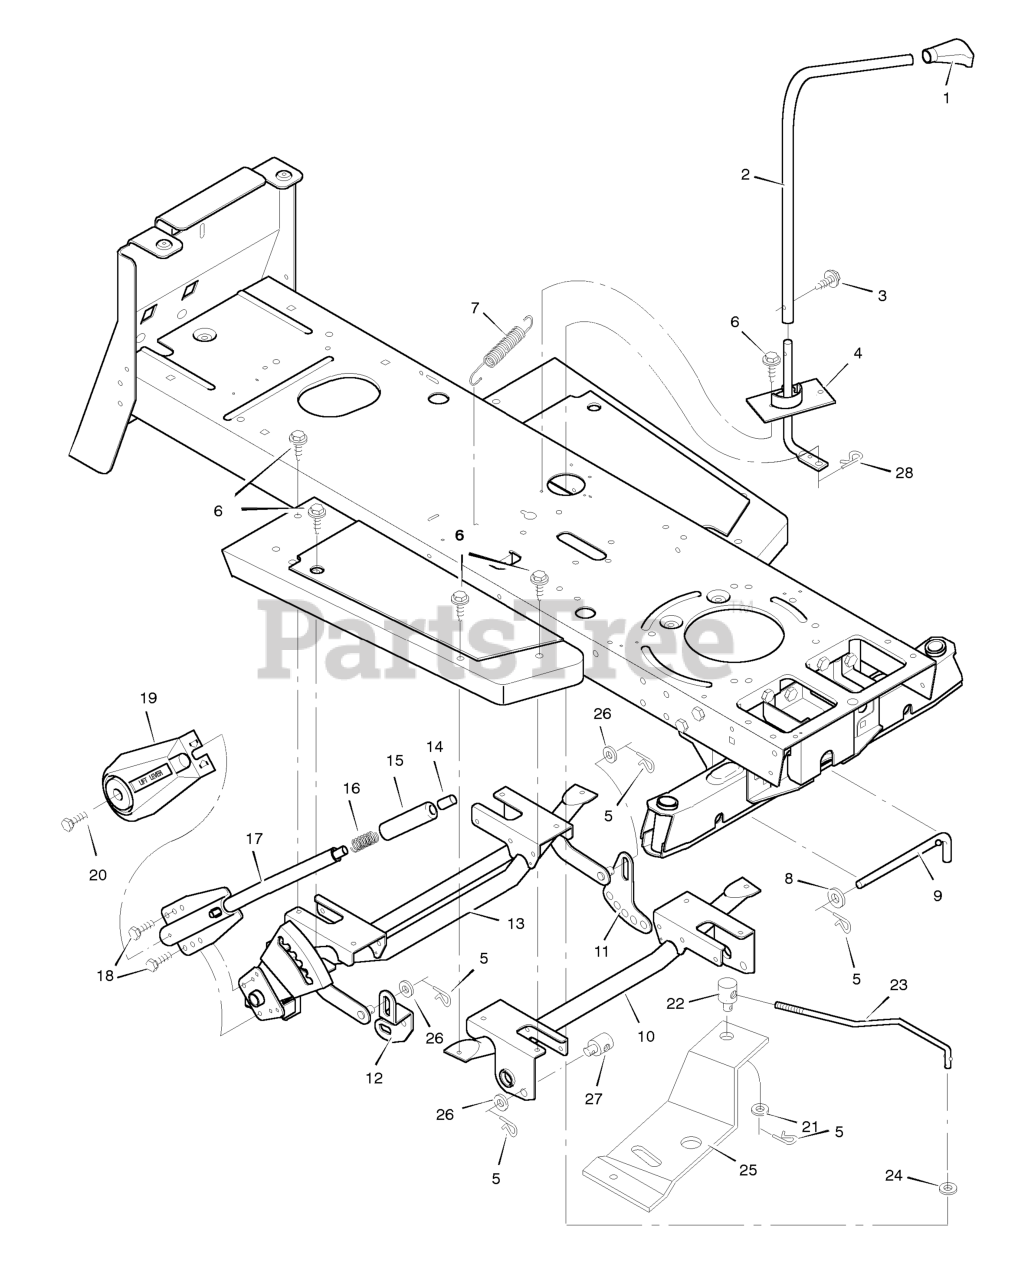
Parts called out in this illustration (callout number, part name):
1	Grip
2	Lever, Blade Control
3	Screw, Hex
4	Control Assembly, Blade
5	Pin, Hair
7	Spring, Extension
9	Pin, Pull
10	Support Assembly, Front
11	Plate, Adjuster
12	Link, Suspension
13	Support, Lifter
14	Button, Push
16	Spring, Compression
17	Handle Assembly
19	Cover, Lift Lever
22	Nut, Adjusting
23	Rod, Blade Control
24	Washer
25	Bracket, Pivot
27	NUT, Adjusting, 1/2-13
28	Pin, Hair
